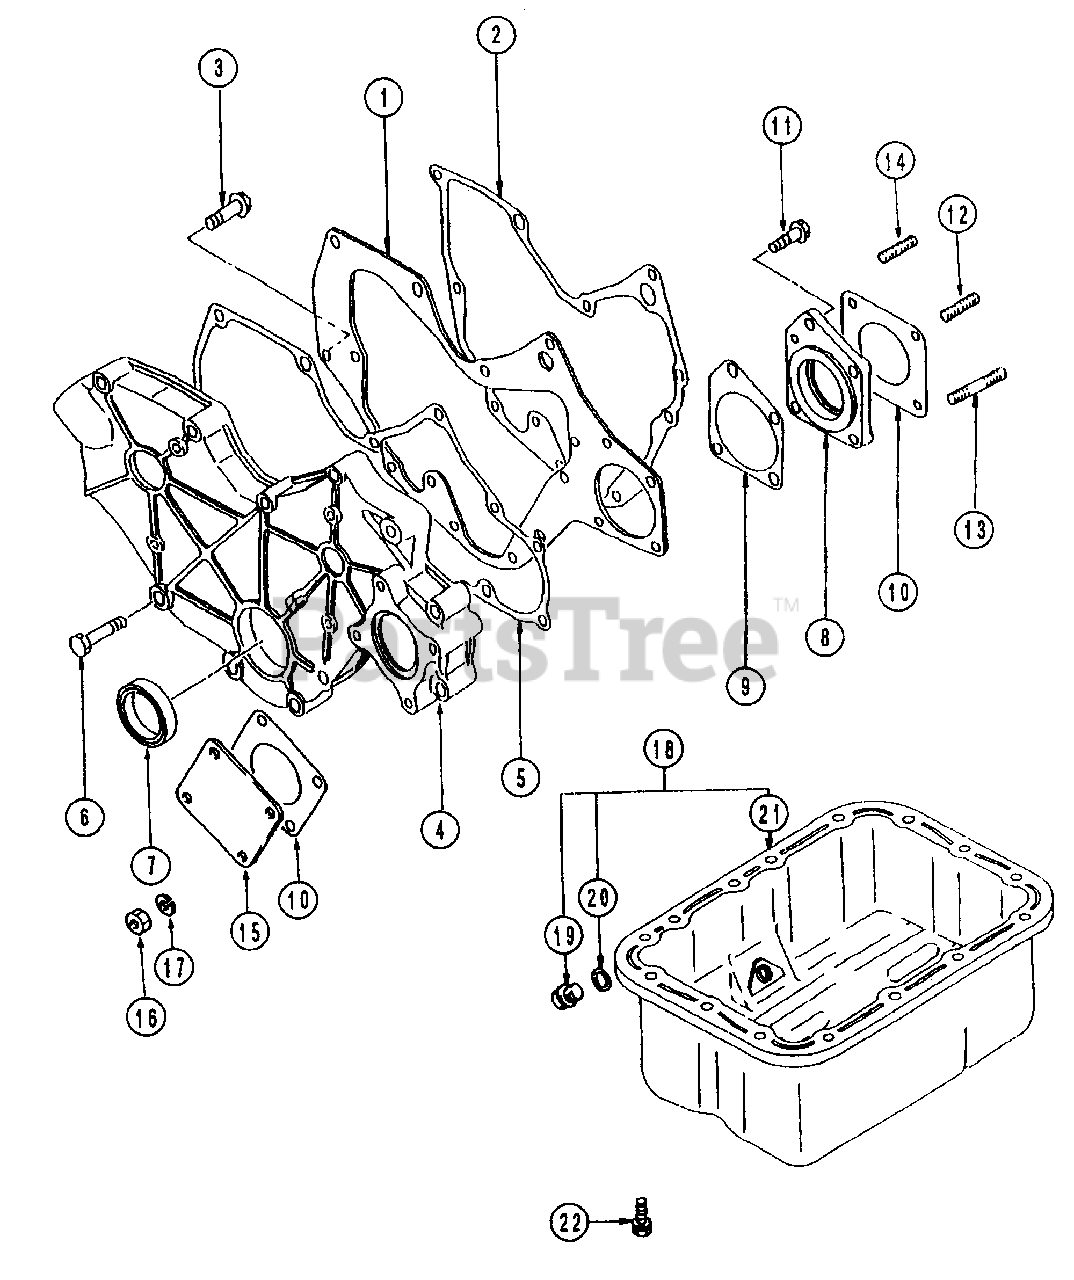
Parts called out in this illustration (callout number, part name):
2	Gasket, Front Plate
3	Bolt, W/Washer
4	Case, Gear, PTO
5	Gasket, Gear
8	Housing, Gear Pump
9	Gasket, Housing
10	Gasket, O/Pump Cover
11	Bolt, W/Washer
12	Stud
15	Cover, Oil Pump
17	Washer, Spring
18	Pan Ass'y, Oil
20	Gasket, Oil Drain
21	Pan, Oil
22	Bolt, W/Washer
